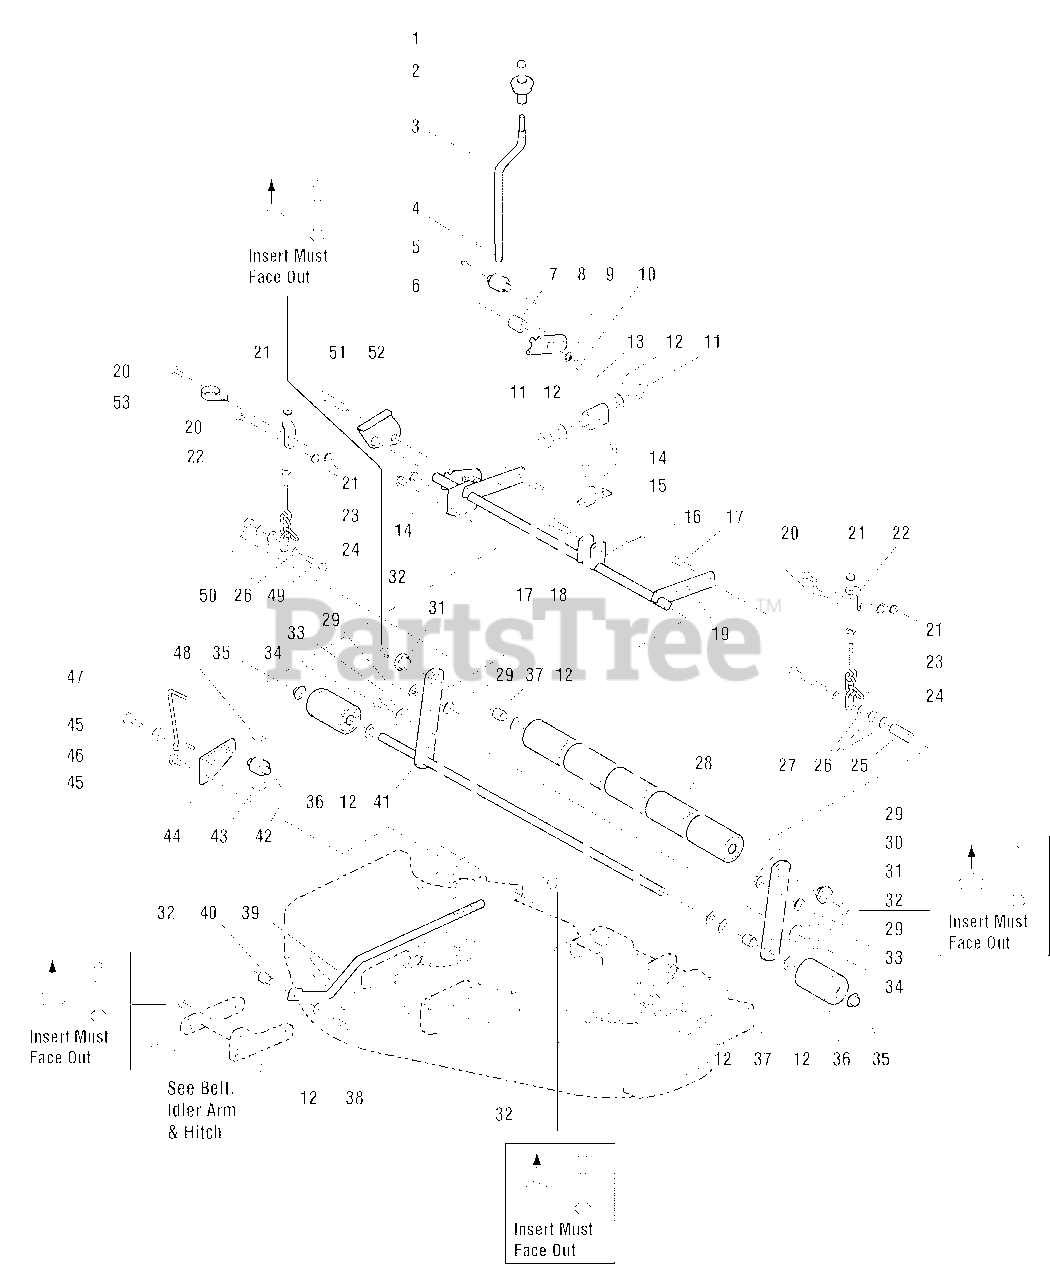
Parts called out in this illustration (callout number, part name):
1	NUT, Push, 3/8, Black
2	KNOB, Spinner
3	CRANK, Height Adjustment, Black
4	PIN, Spring
5	FITTING, Lube
8	ARM, Height Adjust
9	LOCKWASHER, 1/2
10	NUT, Hex, 1/2-13
11	NUT, Hex, 5/8-18
12	WASHER, 5/8
13	TRUNNION
14	CAPSCREW, Hex Washer Head, Taptite, 5/16-18 x 3/4, Black
15	STRAP
16	PIN, Cotter
17	CARRIAGE BOLT, 3/8-16 x 1-1/2
18	PIN, Clevis
19	SHAFT ASSEMBLY
20	CAPSCREW, Hex Head, 5/16-18 x 1
21	NUT, Hex Serrated Flange, 5/16-18
22	BRACKET, Rear Roller
24	CHAIN, 3 Links
26	WASHER, 3/8
27	CAPSCREW, Hex Head, 3/8-16 x 3-3/4, Black
29	NUT, Hex Serrated Flange, 3/8-16
30	BAR, Roller
31	NUT, Hex Adjusting, .99 DIA .687
32	NUT, Hex Lock, Aluminum Insert, 3/8-16
33	WASHER, 1/2
34	BOLT, Shoulder, 3/8-16 X 1.34
35	NUT, Push, 5/8, Black
36	ROLLER, End
37	SPACER, .66 ID
38	CAPSCREW, Hex Head, 3/8-16 x 1-3/4
41	SHAFT & BAR ASSEMBLY
43	WASHER, Detent, Black
45	CAPSCREW, Hex Washer Head, Taptite, 5/16-18 x 1-1/4, Black
46	WASHER, 5/16, Black
47	ROD, Height of Cut
48	WASHER, 1/2, Black
49	CAPSCREW, Hex Head, 3/8-16 x 2
51	CARRIAGE BOLT, 1/2-13 x 2-1/2, Black
52	BRACKET, Height of Cut
